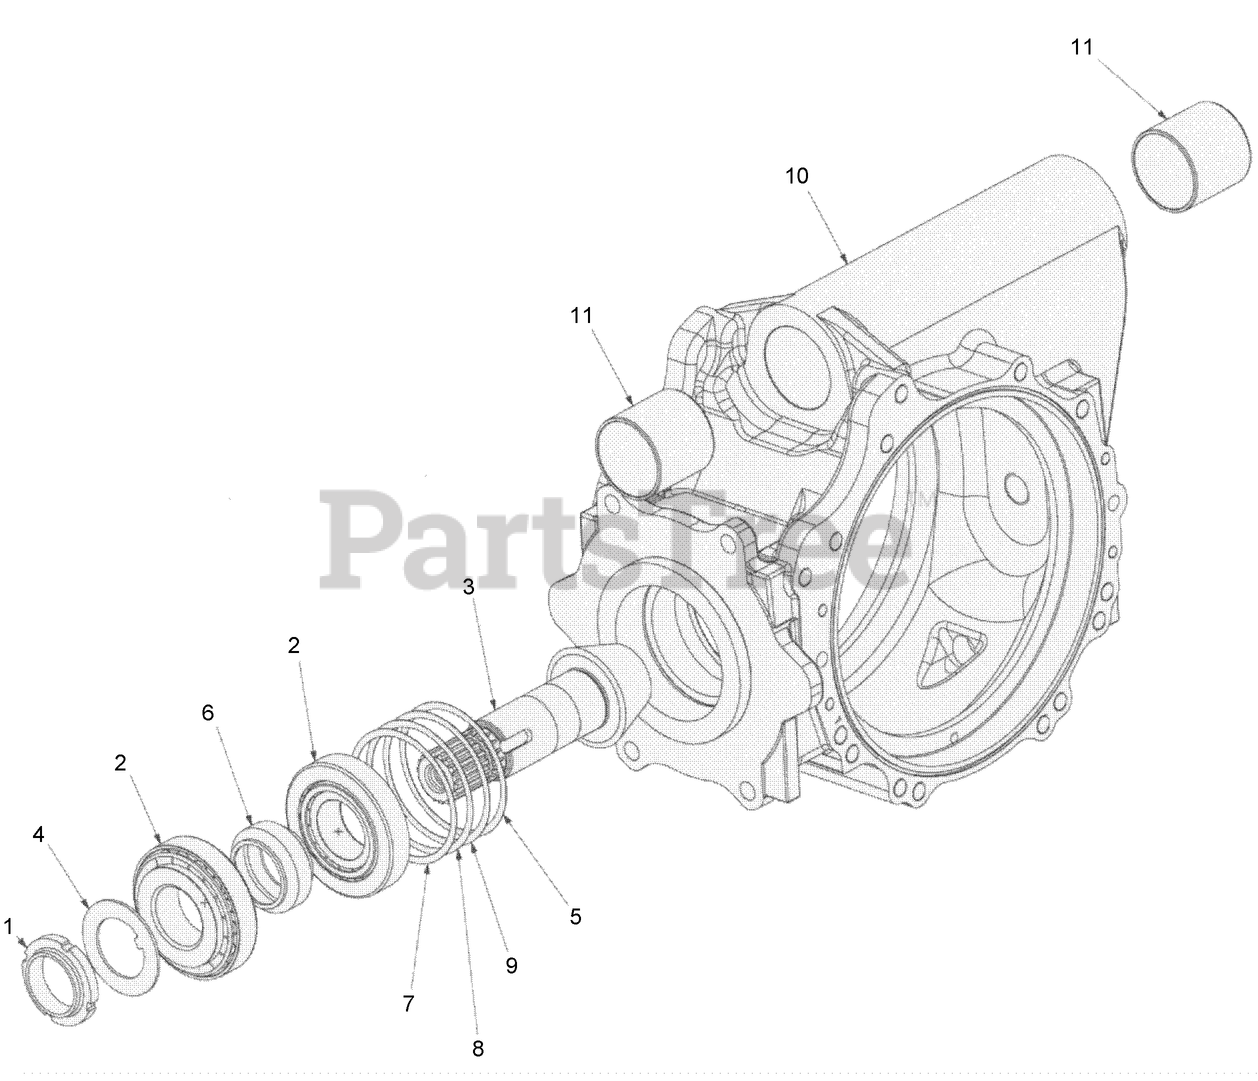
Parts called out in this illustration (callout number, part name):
2	BEARING-Roller, Taper
4	WASHER-Anti-Rotation
6	SPACER-Deformable
10	PIVOT-Upper, Central Housing
